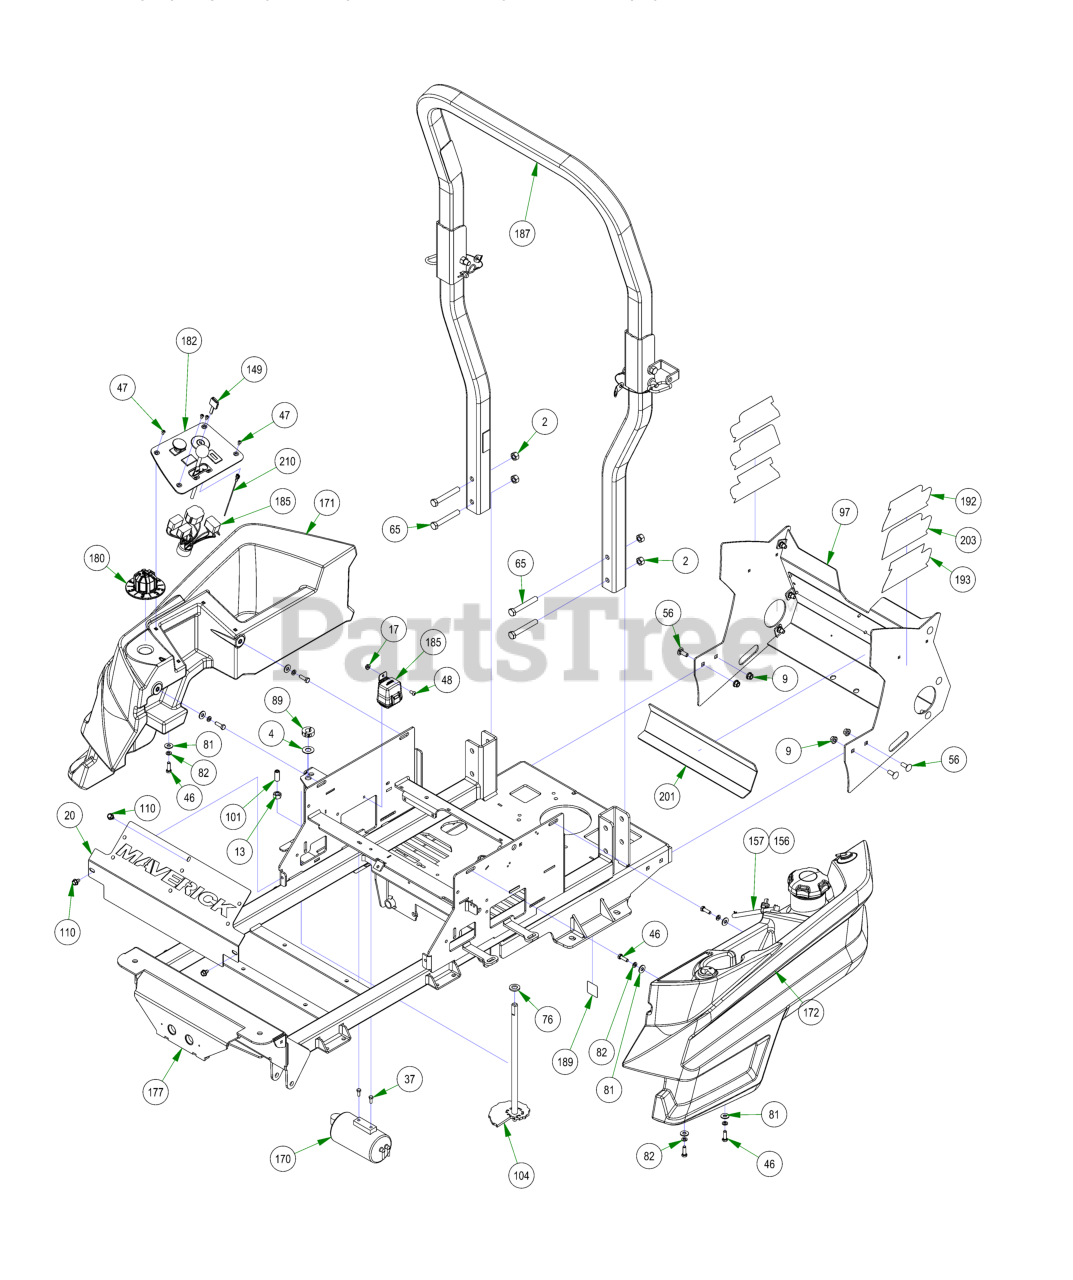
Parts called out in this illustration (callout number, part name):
2	1/2-13 HEX 2-WAY REVERSIBLE CENTER LOCKNUT Grade B ZINC
4	.625 ID x 1.250 OD x .062 THK F/W Nylon
9	3/8-16 NYLON INSERT FLANGE LOCKNUT (GR.F) ZINC
13	1/2-13 HEX NUT ZINC
17	1/4-20 HEX SERRATED FLANGE NUT HARD/ZINC
20	2021 Maverick Cooler Cover Assembly
37	M6-1.0 X 16MM DIN 933 HEX TAP BOLT (CL 8.8) ZINC
46	5/16-18 X 1 HEX CAP SCREW (GR.5) ZINC
47	10-32 X 3/8 BUTTON SOCKET CAP SCREW 18-8 STAINLESS
48	1/4-20 X 1/2 BUTTON SOCKET CAP SCREW 18-8 STAINLESS
56	3/8-16 X 1 CARRIAGE BOLT (GR.5) ZINC
65	1/2-13 X 3-1/2 HEX CAP SCREW (GR.5) ZINC
76	.635 ID X 1.120 OD X .140 THICK FLAT WASHER NYLON
81	5/16 USS FLAT WASHER (7/8 OD) ZINC
82	5/16 SPLIT LOCKWASHER ZINC
89	5/8" Split Collar
97	2022 Maverick Rear Cover Assembly
101	Dial Rod Plunger
104	ZT Deck Height Bar Assembly
110	5/16-18 X 1/2 HWH unslot (F) tcs zinc
149	Ignition Key
156	15" Fuel Line Assembly
157	37" Fuel Line Assembly
170	ZT/Mav EPA Cannister Assy
171	2021 Maverick Right Side Tank
172	2021 Maverick Left Side Tank
177	2023 Maverick Frame - Painted
180	MZ/ZT Deck Height Dial
182	2023 Control Panel Assembly
185	Wiring Harness
187	2016 2x2 ROPS
189	Patent Decal
192	2018 Maverick 726cc Back Plate Cluster
193	2018 Maverick 747cc Back Plate Cluster
201	Heat Shield (Fiberglass Adhesive)
203	MAV 810cc back plate decal
210	2017 MZ/ZT/MAV Tach Wire Assy
